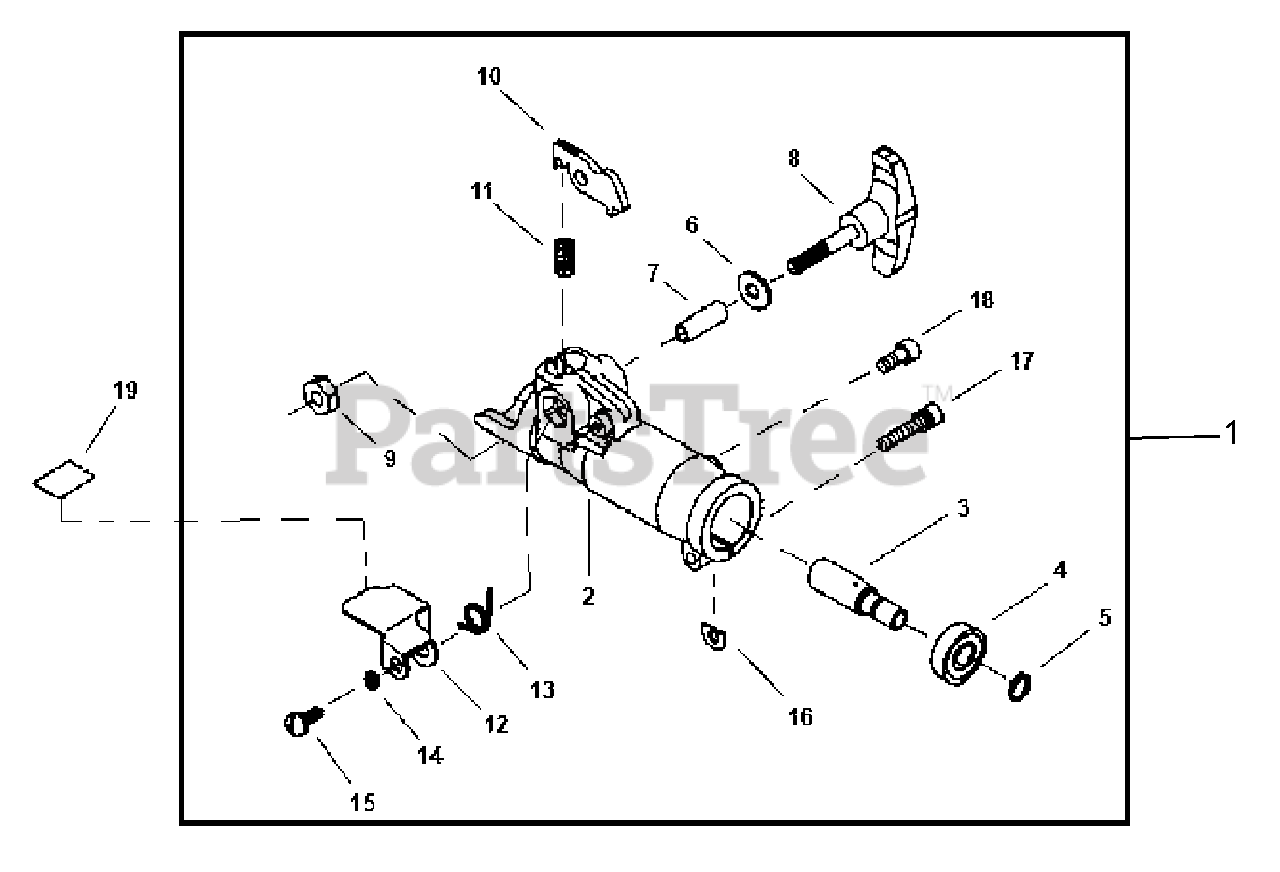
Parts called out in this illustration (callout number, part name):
1	COUPLER ASSY
2	HOUSING, COUPLER
3	SHAFT, COUPLER
4	BEARING, BALL 609ZZ
5	RING, SNAP
6	WASHER 6
7	COLLAR
8	KNOB, COUPLER SCREW
9	NUT 6
10	LATCH
11	SPRING
12	PROTECTOR, LATCH
13	SPRING, TORSION
14	WASHER 5
15	SCREW M5×12
16	D-WASHER
17	SCREW
18	BOLT 5×12
19	LABEL, LATCH INSTRUCTION
